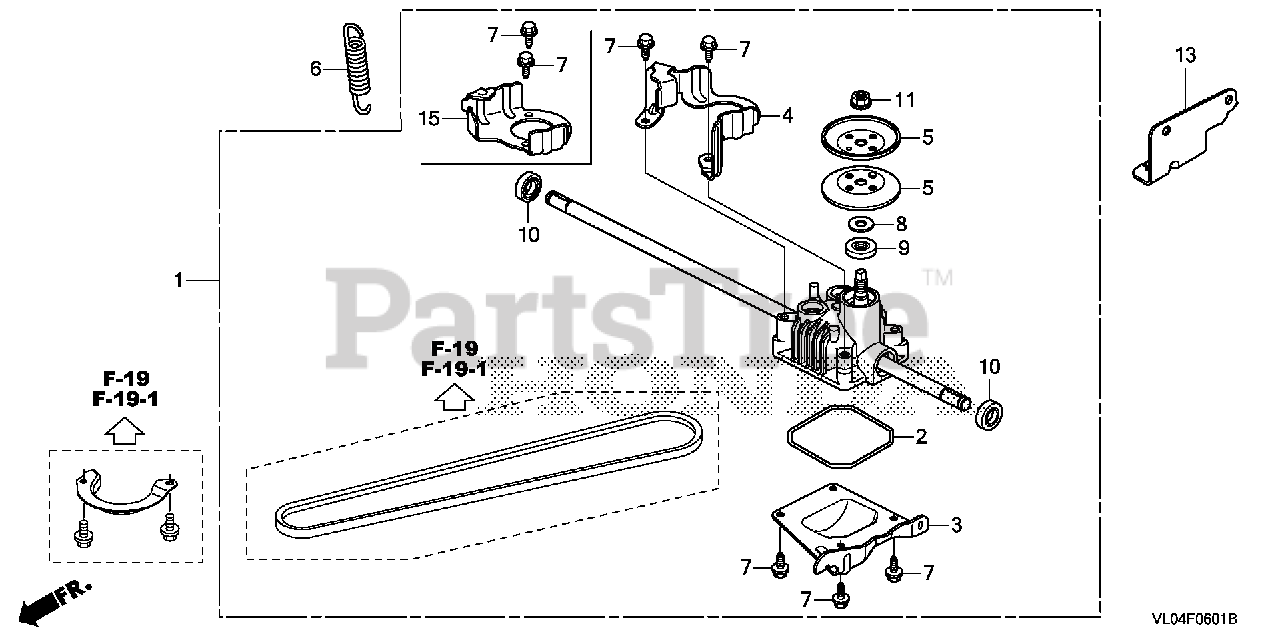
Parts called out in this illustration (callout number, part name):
1	TRANSMISSION ASSY.
2	O-RING, CASE
3	COVER, REDUCTION
4	GUIDE, BELT
5	FACE, DRIVEN
6	SPRING, WHEEL TENSION
7	BOLT, FLANGE (6X12) (CT200)
8	WASHER (10X24)
9	OIL SEAL (12.7X28.6X6.4)
10	OIL SEAL (12.7X22.2X6.4)
11	NUT, FLANGE (10MM)
12	GUIDE, ENGINE BELT (FLYWHL MODELS: 06751-VL0-S00, ROTO-STOP MDLS: 06751-VL0-H00)
13	BRACKET, CABLE MOUNT
14	BOLT, FLANGE (6X14) (CT200)
